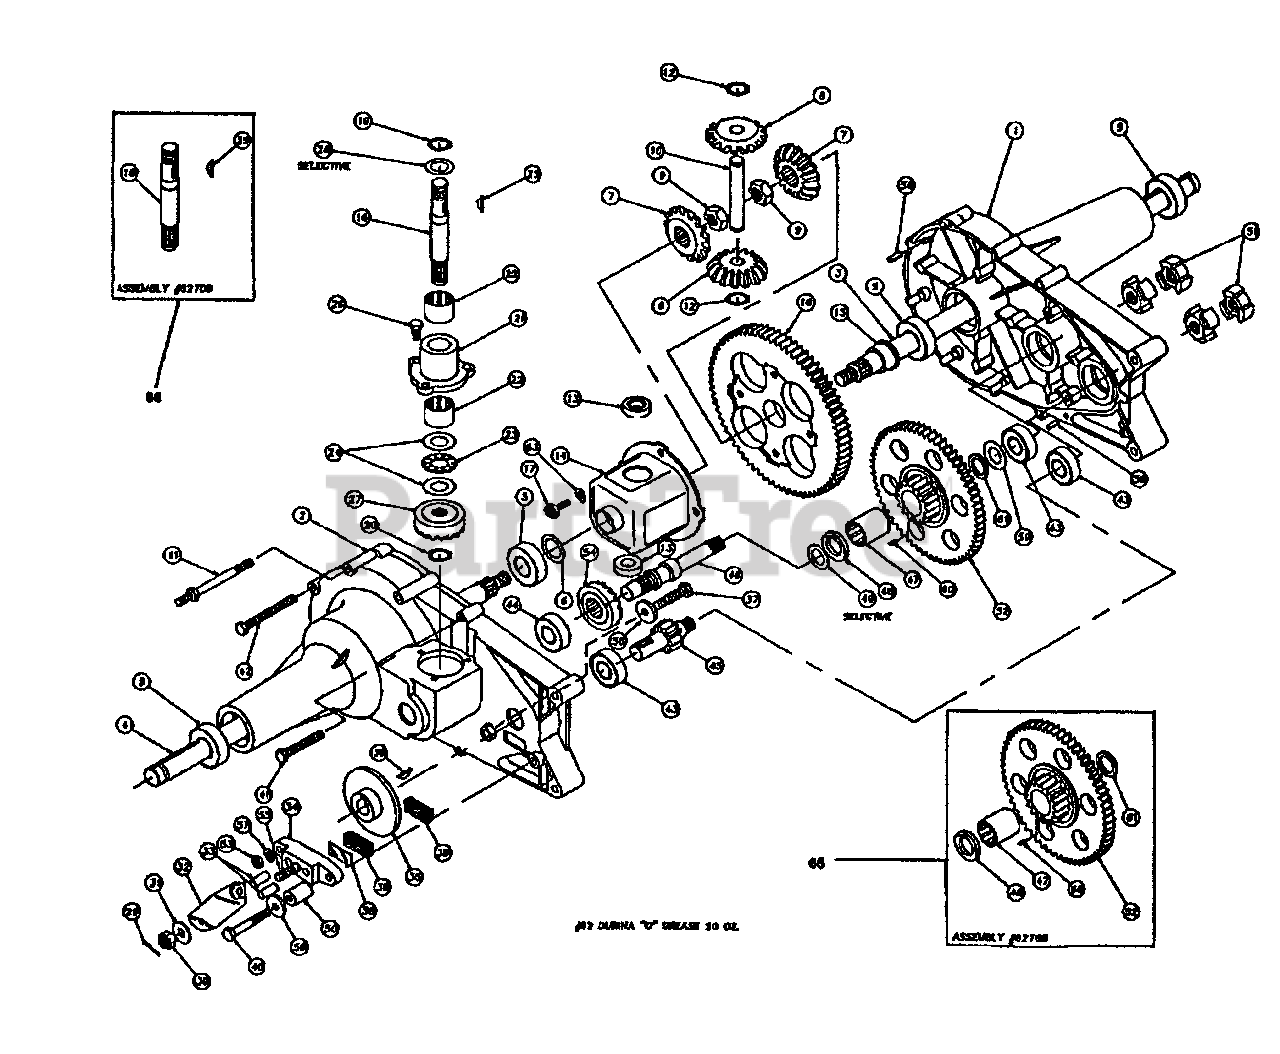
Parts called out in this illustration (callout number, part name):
1	Housing, Half, L.H.
2	Housing, Half, R.H.
3	Axle, L.H.
4	Axle, R.H.
5	Bearing, Ball
6	Washer, Flat 3/4 x 1-1/8 x .030
7	Gear, Miter
8	Gear, Miter
9	Nut, Hex Jam W/Patch 1/2-20
10	Shaft, Cross
11	Screw, Stud
12	Snap, Ring
13	Bearing, Thrust
14	Housing Assembly, Differential
15	Bearing, Flange
16	Gear Differential 72 Tooth
17	Bolt, Torx Head 1/4-28 x 5/8"
18	Shaft, Input
19	Snap, Ring
20	Retaining Ring 7/16"
21	Housing, Input Bearing
22	Bearing, Needle
23	Bearing, Thrust
24	Washer, Flat 5/8 x 1-1/8 x .030
25	Key, Hi-Pro 3/32 x 5/8
26	Screw Hex W/Patch 1/4-20 x 314
27	Gear, Input Pinion 17 Tooth
28	Washer, Flat .62 x 1 x .05
28	Washer, Flat .62 x 1.125 x .060
28	Washer, Flat .62 x 1 x .040
29	Pin, Cotter
30	Nut, Castle 5/16-24
31	Washer, Flat .343 x .88 x .062
32	Arm, Brake Actuator
33	Pin Brake Actuating
34	Brake, Yoke
35	Disc, Brake
36	Key, Hi-Pro 3/16 x 5/8"
37	Screw, Hex 1/4-20 x 1.50
38	Plate, Puck
39	Puck, Brake
40	Screw, Hex W/Patch 1/4-20 x 2.00
41	Screw, Hex Self-Tap 1/4-20 x 2.00
42	Screw, Hex Self-Tap 1/4-20 x 3.00
43	Bearing, Ball
44	Bearing, Ball
45	Shaft, Pinion W/11 Tooth Gear
46	Shaft, Drive
47	Bearing Needle
48	Bronze Thrust Brg. 5/8 x 1-1/4 x 7/64
49	Washer, Flat .62 x 1.0 x .040
49	Washer, Flat .62 x 1.0 x .050
50	Spacer
52	Gear, 60 and 17 Tooth
53	Nut, Hex 1/4-20
54	Gear, Drive Pinion 17 Tooth
55	Bolt, Square Head
56	Washer 15/16 x .285 x .125
57	Washer 1/4" Spring Lock
58	Pin, Roll 3/16" x 1/2"
59	Washer, Flat .82 x 1.0 x .030
60	Pin, Dowel 3/32 x 1/4
61	Seal, Grease
62	Shelf, During-O Grease (20oz.)
63	Washer, Head Spring Lock 1/4"
65	Assembly, Gear, Reduction
66	Assembly, Shaft, Input
